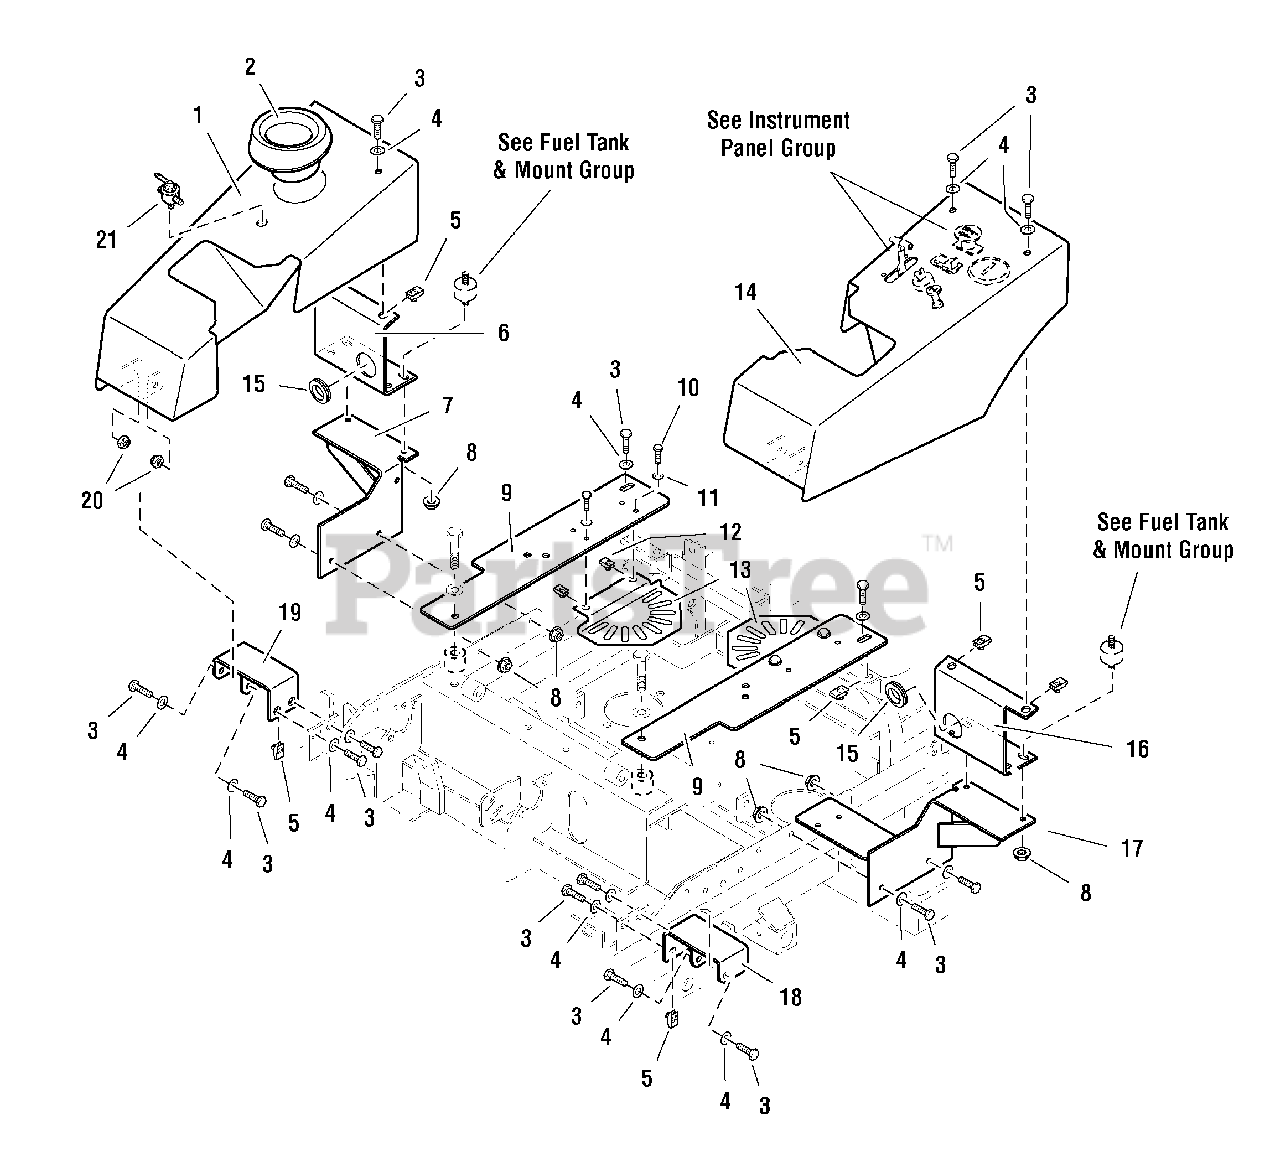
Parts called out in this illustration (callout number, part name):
1	CONTROL COVER-RH
3	CAPSCREW, Hex Hd, 5/16-18 x 1
4	WASHER, 5/16
5	BODY CLIP, 5/16-18
6	CONTROL COVER MOUNT-RH
7	DEBRIS GUARD-RH
8	NUT, Hex, Serrated Flange, 5/16-18
9	FAN SHIELD MOUNT
10	BOLT, 1/4-20 X 1", GD
11	WASHER, 1/4 SAE (5025154)
12	BODY CLIP, 1/4-20
14	CONTROL COVER-LH
16	CONTROL COVER MOUNT-LH
17	DEBRIS GUARD-LH
18	CONTROL PANEL PIVOT-LH
19	CONTROL PANEL PIVOT-RH
20	NUT, Hex, Nylon Lock, 5/16-18
21	FUEL SHUT OFF VALVE
